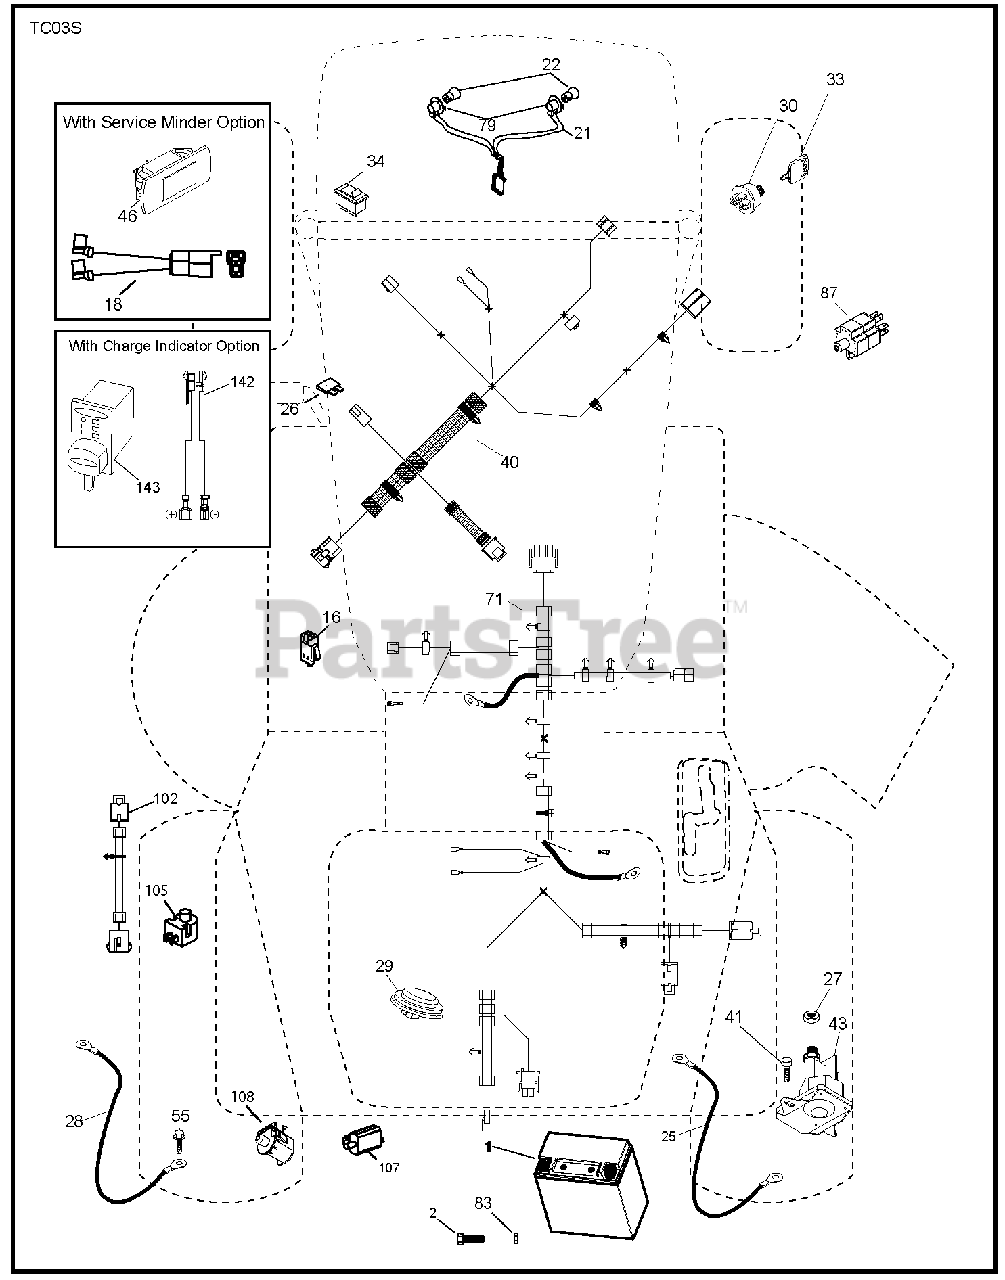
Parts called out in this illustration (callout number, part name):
16	SWITCH INTERLOOK PUSH-IN
21	HARNESS.LIGHT W/4152J BULBS
22	LIGHTBULB
26	FUSE 20AMP
27	NUT
29	SWITCH.SEAT.DELTA.OPC.
30	SWITCH.IGN.DELTA.W.LGH.ROS
33	KEY.CHAIN.BLISTER.PACK.GEN.INT
34	SWITCH LT
41	SCREW
43	SOLENOID.W/BRASS.PLUNG
55	SCREW 5/16"
79	BULB HOLDER ASM.
102	HARNESS PIGTAIL PCH TEX ROS
105	REVERSE SWITCH
108	SWITCH.SNAPMOUNT.NC
